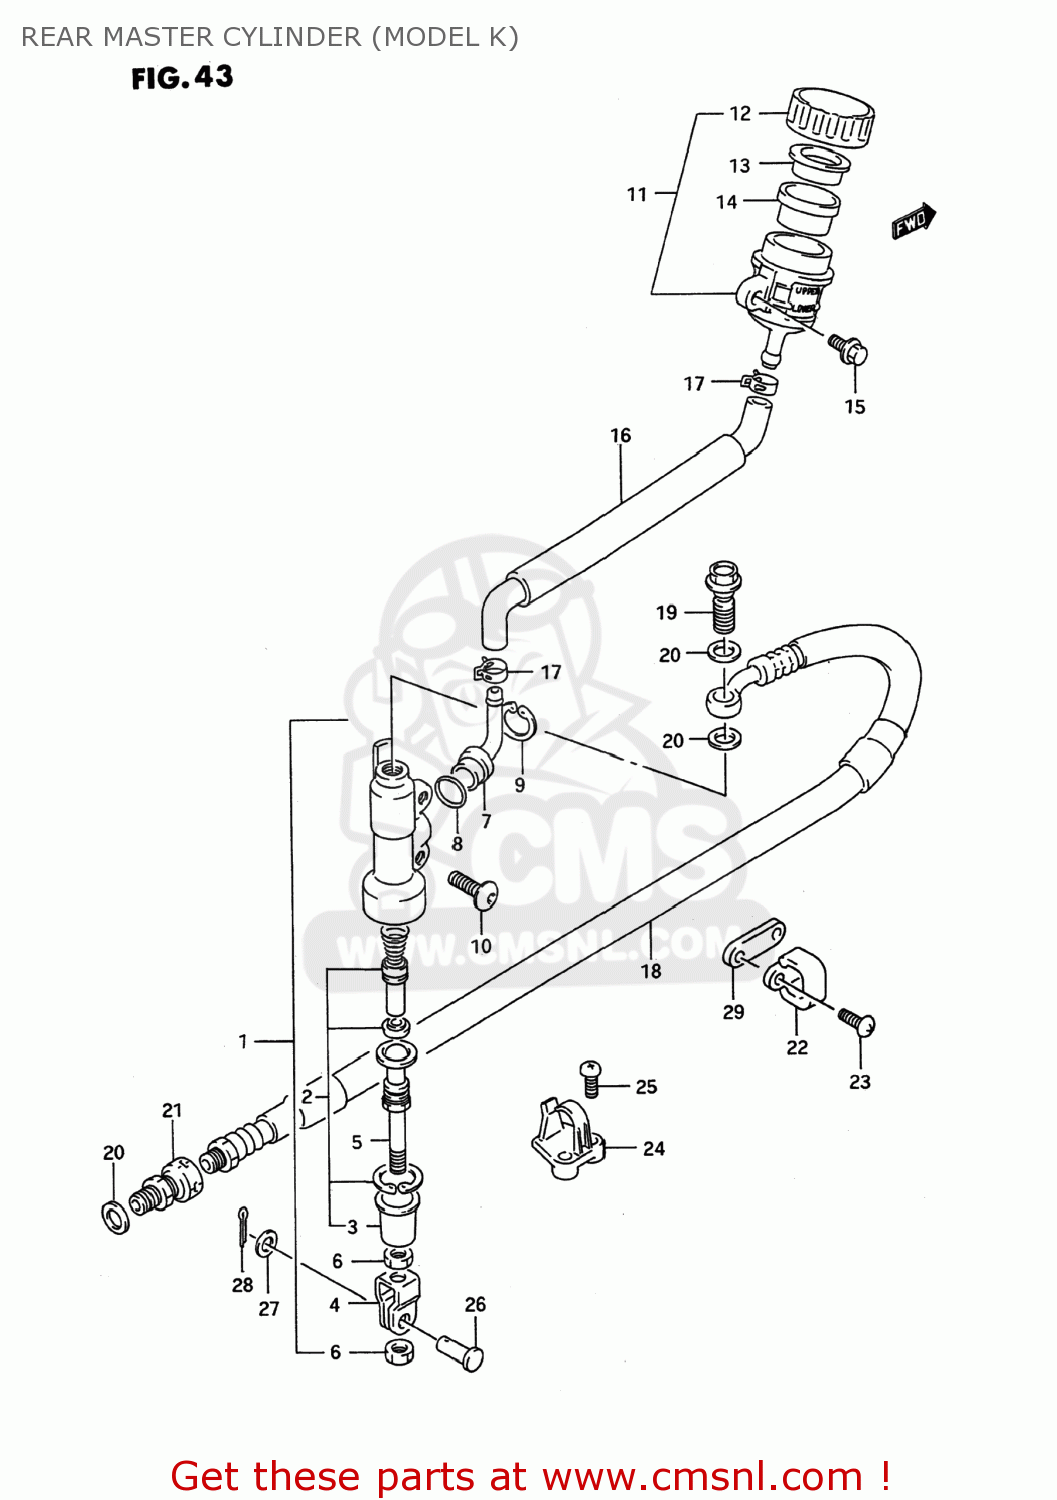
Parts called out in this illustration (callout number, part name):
1	CYLINDER ASSEMBLY,REAR MASTER
2	PISTON/CUP SET
3	BOOT
4	YOKE
5	ROD,PUSH
6	NUT
7	CONNECTOR
8	O RING
9	CIRCLIP
10	BOLT(6X18)
11	TANK ASSY,RESERVOIR
12	CAP
13	PLATE
14	DIAPHRAGM
15	BOLT
16	HOSE,RESERVOIR
17	CLAMP,RESERVOIR HOSE
18	HOSE COMP,REAR BRAKE
19	BOLT UNION
20	WASHER(10X15X1.5)
21	ADAPTOR,BRAKE HOSE
22	GUIDE,RR BRAKE HOSE
23	SCREW
24	GUIDE,RR BRAKE HOSE
25	SCREW
26	PIN(8X20)
27	WASHER(8.5X13X1.6)
28	PIN
29	SEAT,RR BRAKE HOSE GUIDE
